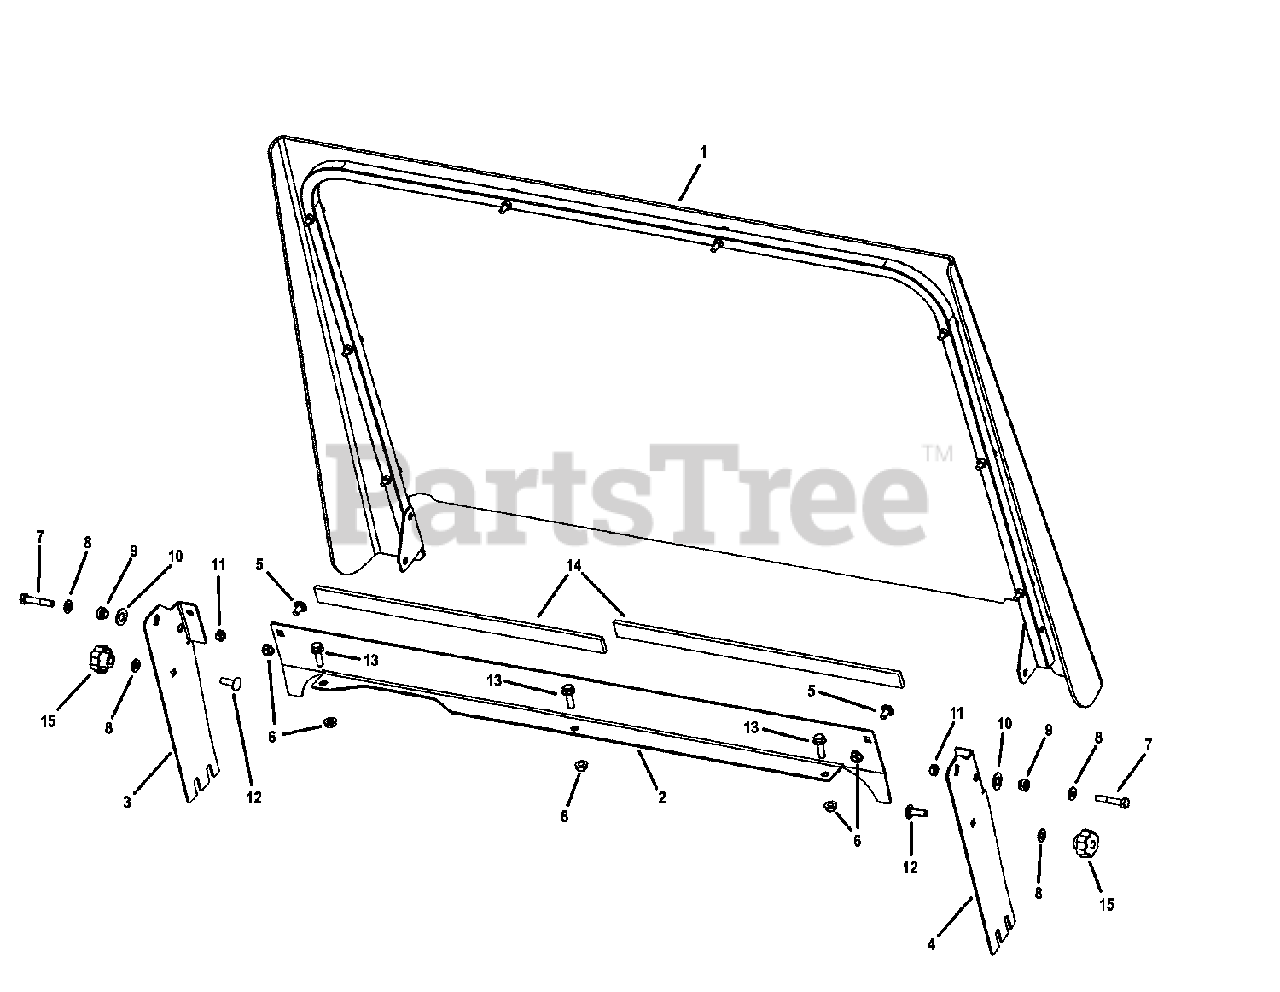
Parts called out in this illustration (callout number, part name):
1	ASSY, WINDSHIELD FRAME
2	BRKT, CROSS SUPPORT, UV WS
3	BRKT, WINDSHIELD, LH
4	BRKT, WINDSHIELD, RH
5	RHSSNB,5/16CX5/8
6	FLN, 5/16-18 YZ
7	HHCS, 5/16-24 X 1.75 GR5 YZ
8	FW,.34X.69X.08
9	BSHG, DIFF LK,.328X.625X.41
10	FLW, .47 X .92 X .065 YZ
11	HCLN, 5/16-24 YZ
12	RHSSNB, 5/16-18 X 1 GR 5 YZ
13	HFLB, 5/16-18 X 1 YZ
14	STRIP, SPONGE RUBBER, 1/4 THK X 1 WIDE
15	KNOB, FLUTED 5/16-18 YEL
